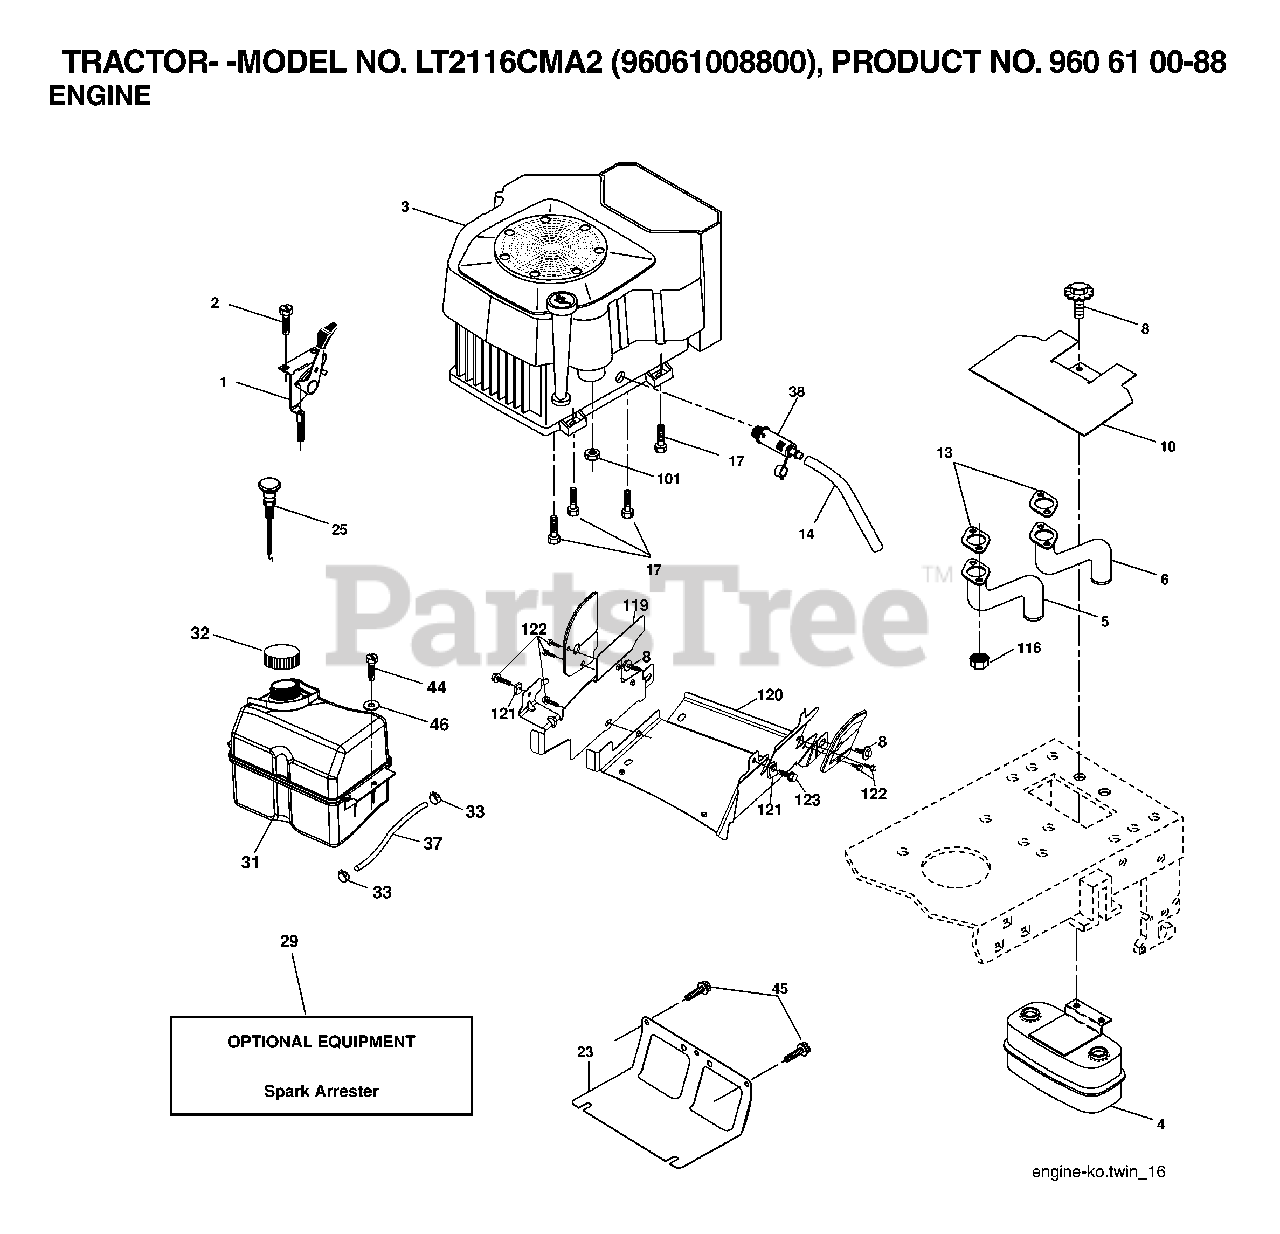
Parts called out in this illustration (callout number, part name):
2	SCREW
4	MUFFLER.TWIN.CYL.LOW.TONE
5	PIPE-EXHAUST LH
6	PIPE-EXHAUST RH
8	BOLT, 5/16-18 X 1 3/4
10	RP SHIELD HEAT MUFFLER
14	TUBE, DRAIN OIL ASM.
23	SHEILD.BROWNING.DBR.GUARD
25	CONTROL, CHOKE, 37", PUSH
29	ARRESTER SPARK (OPTIONAL)
31	TANK FUEL
32	FUEL CAP
33	HOSE CLAMP
37	LINE.FUEL.20
38	PLUG DRAIN OIL EASY
44	SCREW HEXWSHR 1/4-20X3/4
45	SCREW, 3/8-16X3/4
101	FLANGE NUT
116	NUT.HEX.FLANGE.TOPLOCK
122	SCREW.1/4-20X5/8
123	SCREW, 5/16-18 X 1/2
